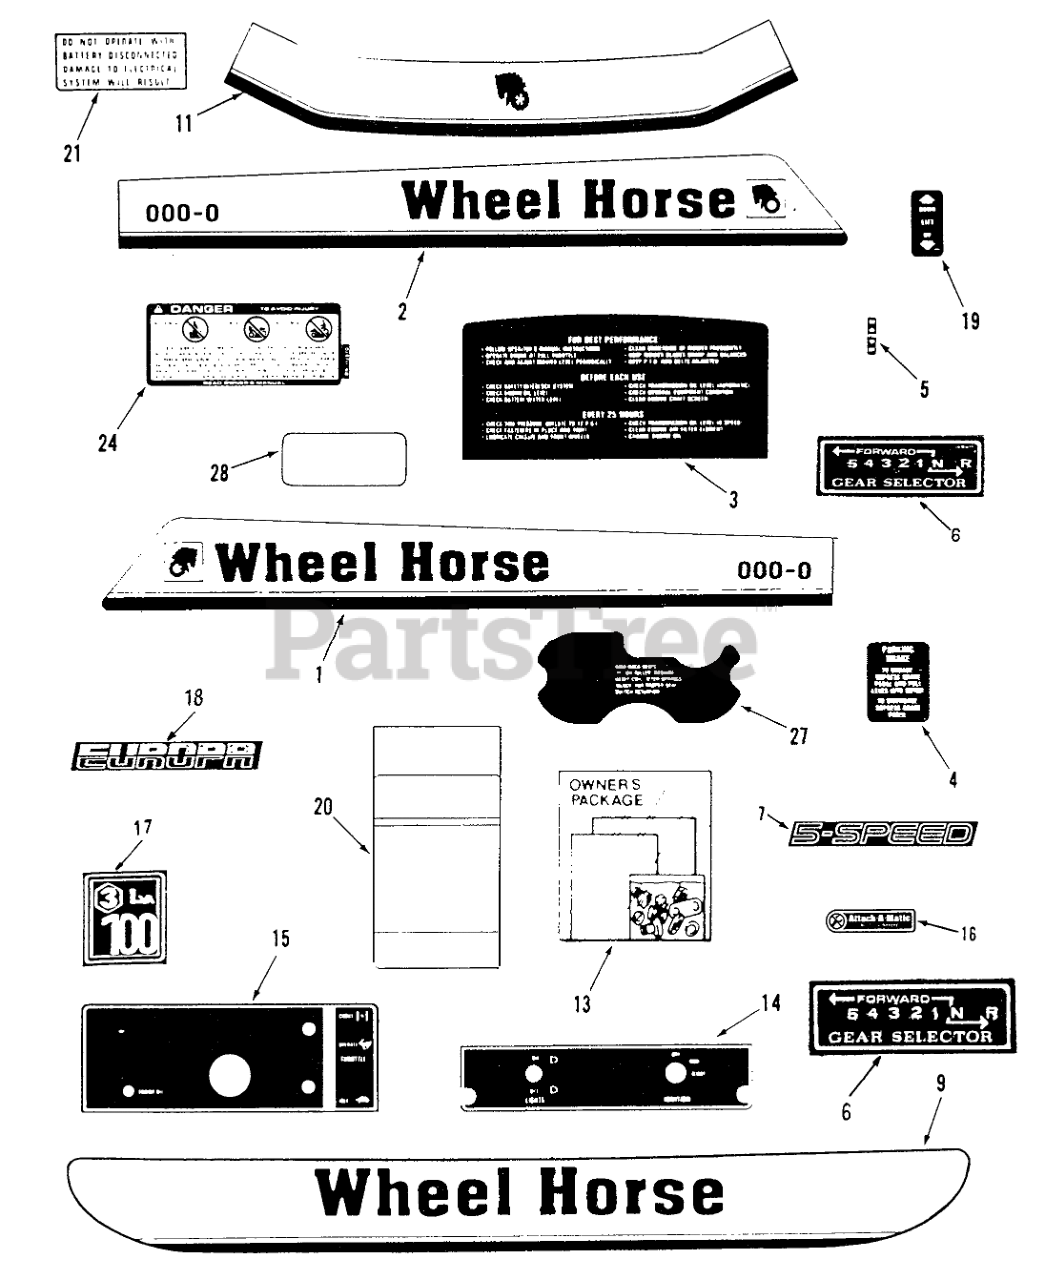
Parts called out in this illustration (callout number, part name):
1	DECAL-HOOD R.H.
2	DECAL-HOOD L.H.
3	DECAL-REAR HOOD
4	DECAL-PARKING-BRAKE
5	DECAL PTO CLUTCH
6	DECAL SHIFT
7	DECAL 5SPD
9	DECAL-FENDER
11	DECAL-FRONT HOOD
14	DECAL BACK PLATE
15	DECAL-LOWER DASH
16	Decal-Attac-O-Matic
17	DECAL-EUROPE
18	DECAL-EUROPA
19	DECAL-LIFT
20	MAINTENANCE-DECAL
21	DECAL ELECT SYSTEM
24	DECAL-DANGER
27	DECAL-SEAT LIFTER
28	DECAL-OVERLAY
